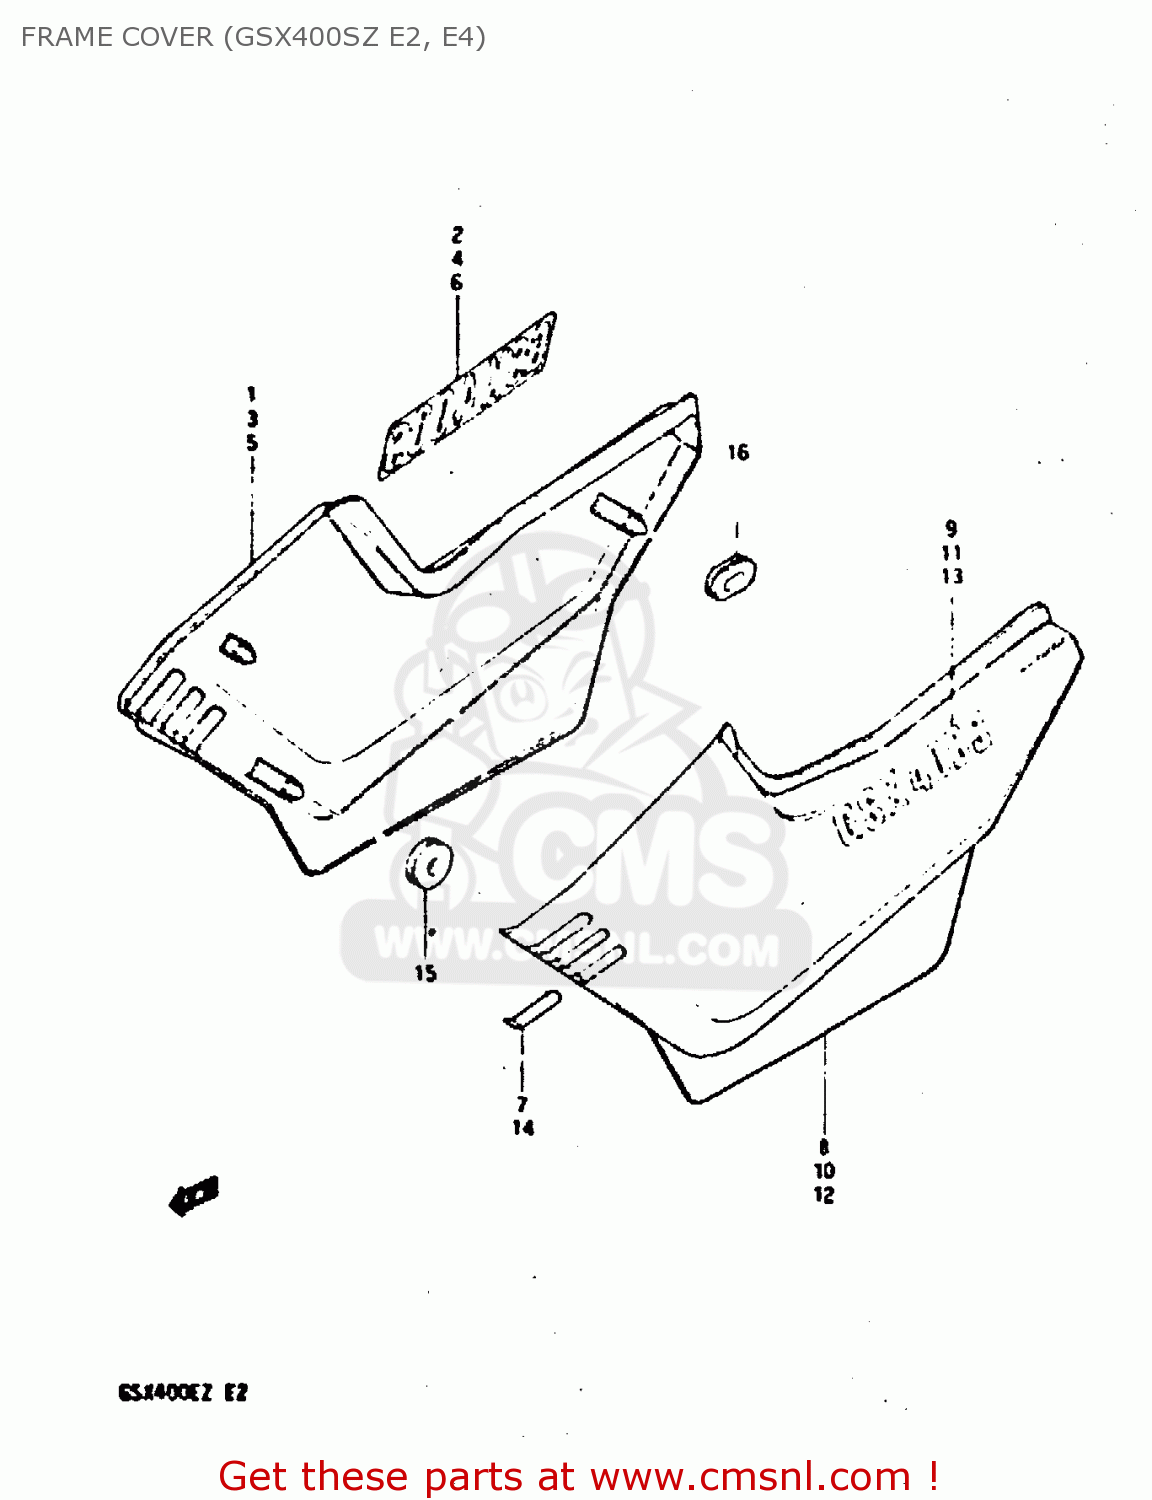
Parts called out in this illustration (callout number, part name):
1	COVER,FRAME,RIGHT
2	EMBLEM, LH
3	COVER, FRAME RH (SILVER)
4	EMBLEM, LH
5	COVER, FRAME RH (BLACK)
6	EMBLEM, LH
7	LABEL,FRAME COVER DENT
8	COVER,FRAME,LEFT
9	EMBLEM, LH
10	COVER, FRAME LH (SILVER)
11	EMBLEM, LH
12	COVER, FRAME LH (BLACK)
13	EMBLEM, LH
14	LABEL,FRAME COVER
15	CUSHION
16	CUSHION
